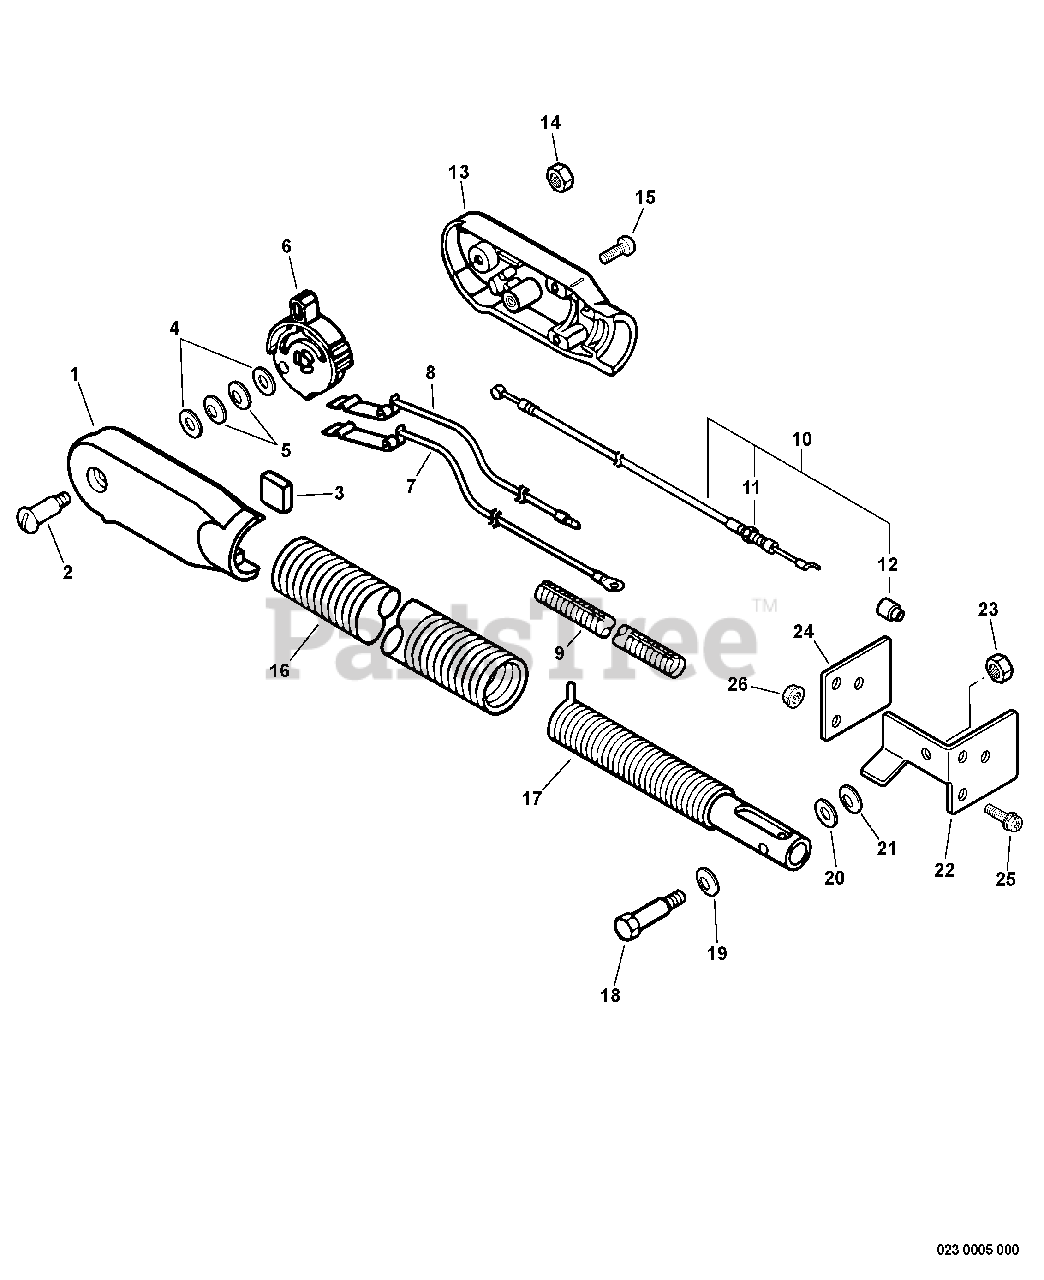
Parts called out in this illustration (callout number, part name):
1	GRIP, LEFT THROTTLE
3	PAD, FOAM
4	WASHER 6.5×15.5×0.6
5	WASHER, FRICTION 6.6×14.3
6	LEVER, THROTTLE
8	LEAD - IGNITION
9	TUBE, PROTECTIVE - CORRUGATED
10	THROTTLE CABLE ASSY
11	NUT, HEX M6
12	CAP, DUST
13	GRIP, RIGHT THROTTLE
14	NUT, LOCK 4
16	TUBE, OUTER FLEX
17	TUBE, SPRING
19	WASHER, WAVE
20	WASHER 8
21	WASHER - 8
22	BRACKET, MOUNTING
25	SCREW 5×16
26	NUT, FLANGE M5
